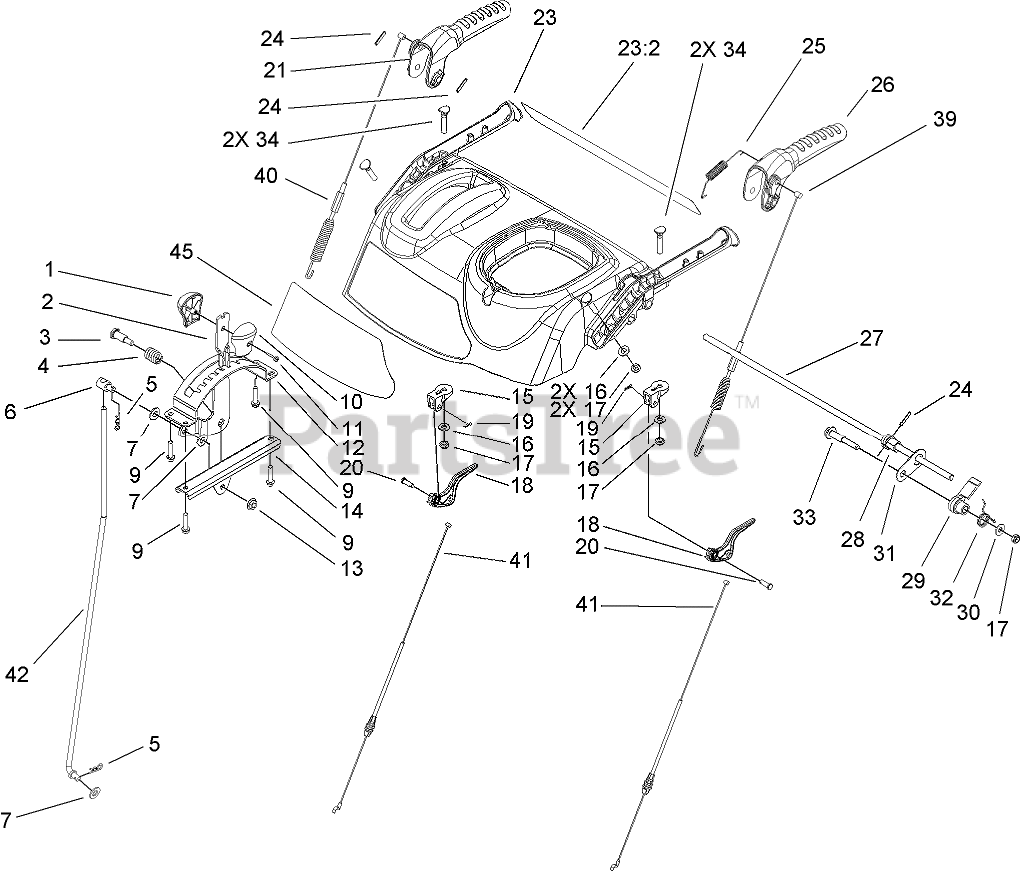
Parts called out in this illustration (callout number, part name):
1	KNOB-SHIFT, RH
2	SELECTOR-SPEED
3	SCREW-SHOULDER
4	SPRING-COMPRESSION
5	PIN-COTTER
6	TRUNNION-ROD
7	WASHER-FLAT
9	SCREW-PLASTITE
10	KNOB-SHIFT, LH
11	SCREW-PPH
12	GUIDE-SELECTOR, SPEED
13	NUT-HF
14	MOUNT-SELECTOR, SPEED
15	MOUNT-CLUTCH, LEVER
16	WASHER-FLAT
17	NUT-LOCK, NI
18	LEVER-CLUTCH
19	PIN-HAIR
20	PIN-CLEVIS
21	LEVER-AUGER
23	CONTROL PANEL ASM
23:2	DECAL-CONTROL PANEL, BACK
24	PIN-SPRING
25	SPRING-TENSION
26	LEVER-TRACTION
27	ROD-LOCKOUT
28	CAM-LOCKOUT
29	LATCH-LOCKOUT
30	WASHER-FLAT
31	LINK-LOCKOUT
32	SPRING-TORSION
33	SCREW-SHOULDER
34	SCREW-HANDLE
39	CABLE-TRACTION
40	CABLE-AUGER
41	CABLE-CLUTCH
42	ROD-SHIFT
45	DECAL-PANEL, CONTROL
